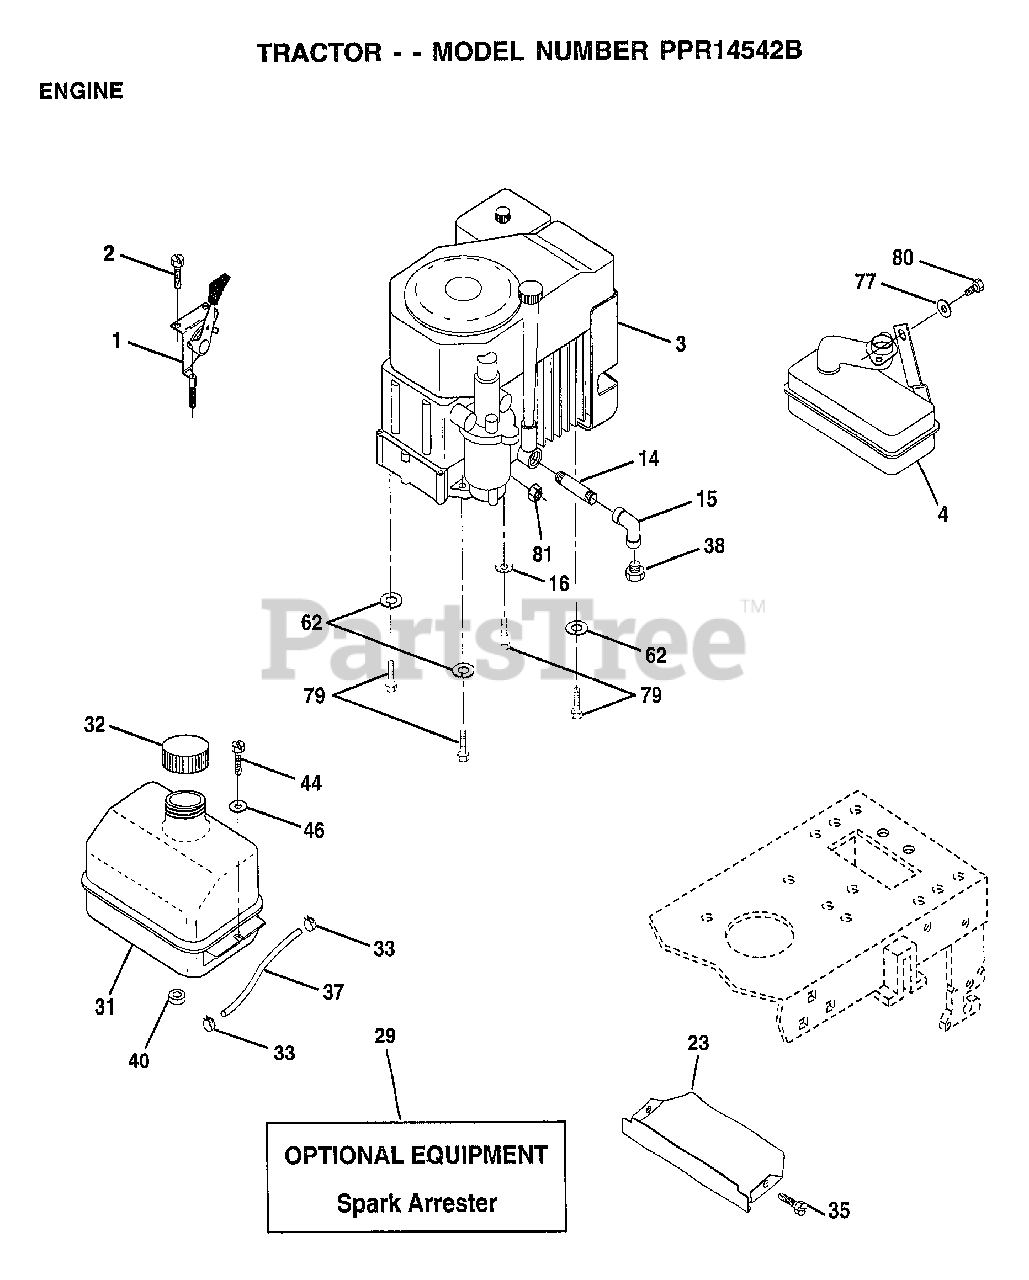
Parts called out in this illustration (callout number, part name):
1	CONTROL.THROTTLE/CHOKE
2	SCREW LT
4	MUFFLER
14	PIPE NIPPLE
15	ELBOW
16	LOCKWASHER.5/16.E
23	SHIELD.BRN/DBR.GD
31	TANK.FUEL.LT.
32	CAP ASM FUEL
33	HOSE CLAMP
35	SCREW
37	LINE FUEL
44	SCREW HEX CRT
46	WASHER
62	LOCKWASHER
80	BOLT
81	NUT
